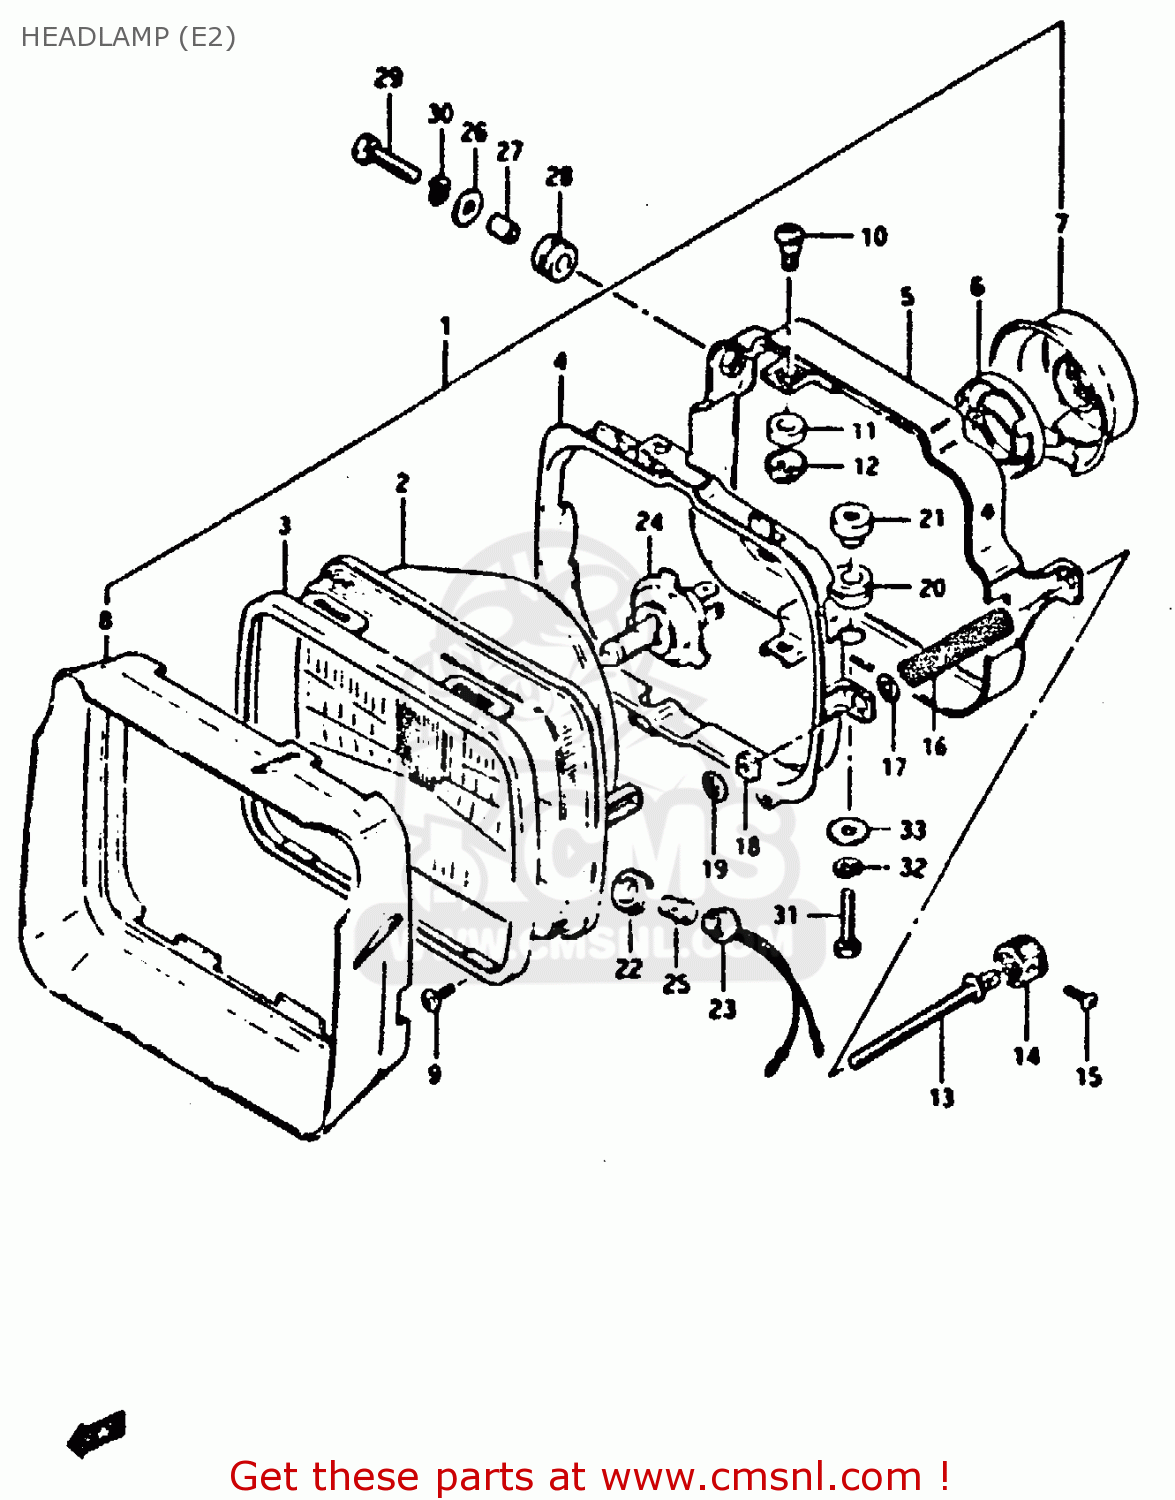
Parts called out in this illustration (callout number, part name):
1	HEADLAMP ASSY
2	UNIT
3	RETAINER
4	RING,MOUNTING
5	HOUSING
6	HOLDER
7	COVER,HEADLAMP SOCKET
8	SHADE,HEADLAMP UNIT
9	SCREW
10	SCREW
11	SPACER
12	NUT,ADJUSTING
13	SCREW,ADJUSTING
14	KNOB,ADJUSTER
15	SCREW
16	SPRING
17	WASHER
18	NUT
19	NUT,HEADLAMP ADJUSTER
20	CUSHION
21	NUT
22	JOINT,RUBBER
23	SOCKET
24	BULB(12V60/55W,H4)
25	BULB(12V4W)
26	WASHER
27	SPACER (6.1X8X9.5)
28	CUSHION
29	BOLT
30	LOCK WASHER
31	SCREW(6X20)
32	LOCK WASHER
33	WASHER
